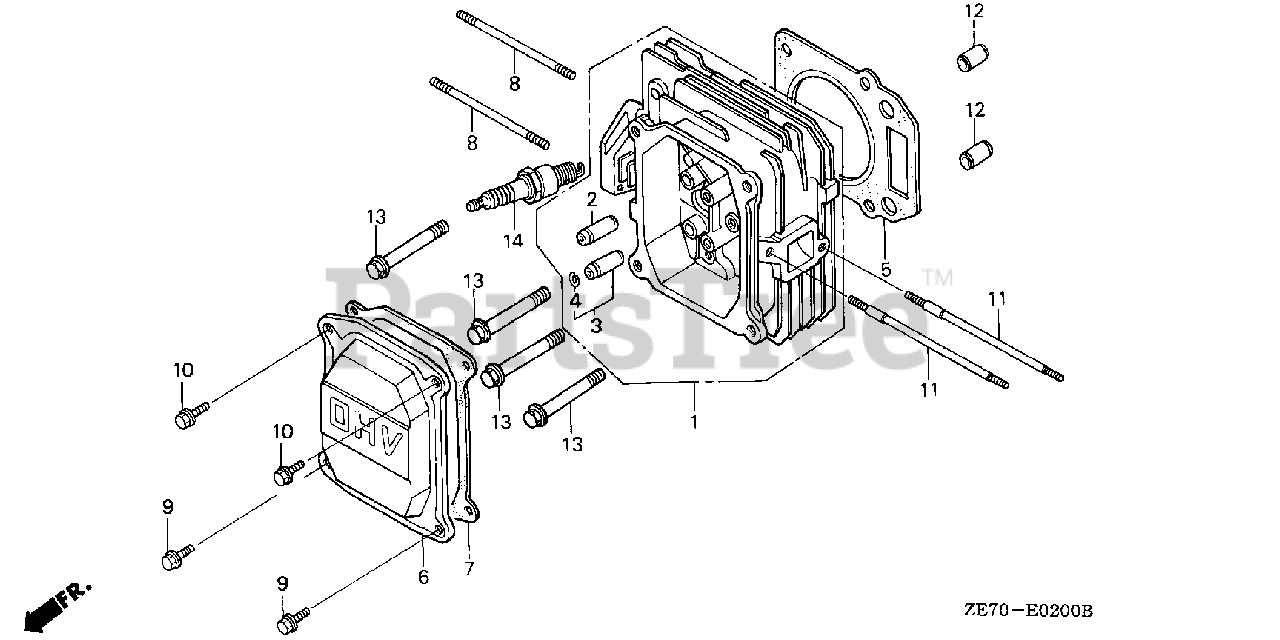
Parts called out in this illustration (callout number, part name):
1	CYLINDER HEAD
2	GUIDE, VALVE (OVER SIZE)
3	GUIDE, EX. VALVE (OVER SIZE)
4	CLIP, VALVE GUIDE
5	GASKET, CYLINDER HEAD
6	COVER, HEAD
7	GASKET, HEAD COVER
8	BOLT, STUD (6X82)
9	BOLT, FLANGE (6X12) (CT200)
10	BOLT, FLANGE (6X14) (CT200)
11	BOLT, STUD (6X109)
11	BOLT, STUD (6X112)
12	PIN, DOWEL (10X16)
13	BOLT, FLANGE (8X50)
14	SPARK PLUG (BPR4ES) (NGK)
14	SPARK PLUG (W14EPR-U) (DENSO)
14	SPARK PLUG (BPR5ES) (NGK)
14	SPARK PLUG (W16EPR-U) (DENSO)
14	SPARK PLUG (BPR6ES) (NGK)
14	SPARK PLUG (W20EPR-U) (DENSO)
